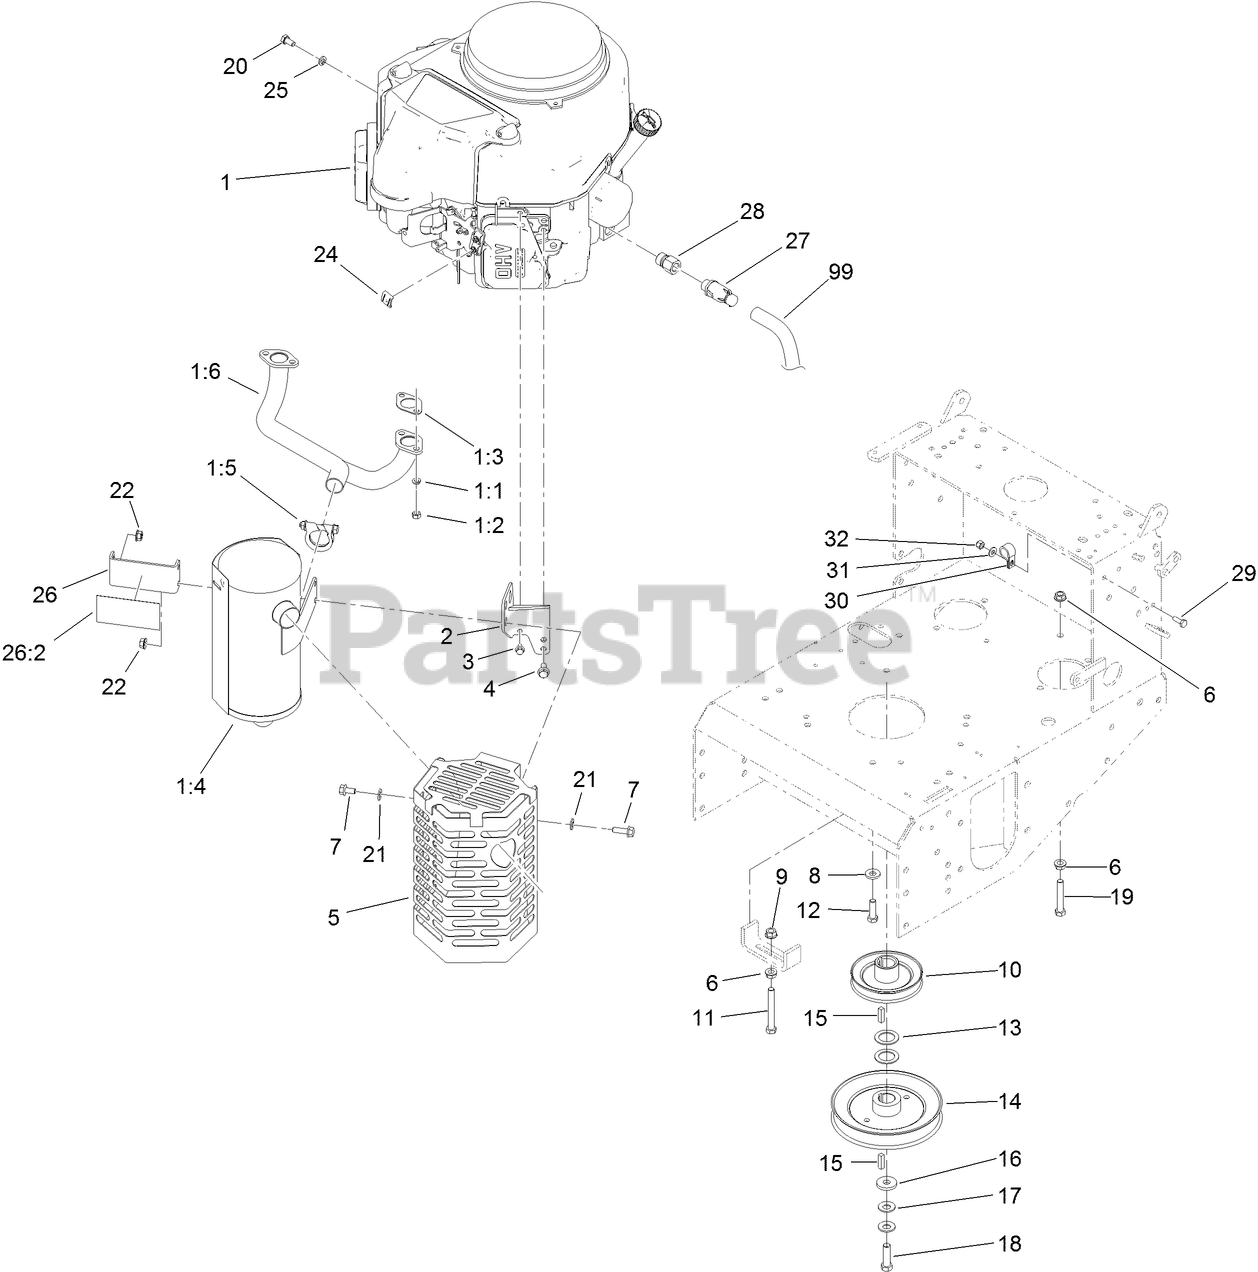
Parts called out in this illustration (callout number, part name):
1:1	WASHER-LOCK
1:3	GASKET-EXHAUST
1:4	MUFFLER-ENGINE
1:5	CLAMP-MUFFLER
1:6	MANIFOLD-EXHAUST
2	BRACKET-MUFFLER
3	SCREW-HHF
4	SCREW-HHF
5	MUFFLER SHIELD ASM
6	NUT-HHF, WHIZ
7	SCREW-HHF
8	WASHER-BELLEVILLE
9	NUT-HF
10	PULLEY
11	SCREW-HH
12	SCREW-HH
13	WASHER-SPACER
14	PULLEY
16	WASHER
17	WASHER-SPRING
18	SCREW-HH
19	SCREW-HH
20	SCREW-HH
21	WASHER-SPRING
22	NUT-HF, LOCK
24	CLAMP-CABLE
25	WASHER-LOCK
26	MUFFLER BRACKET ASM
26:2	FOIL-SHIELD, BRACKET
27	VALVE-DRAIN, OIL
28	ADAPTER
29	SCREW-HH
30	CLAMP-CABLE
31	WASHER-FLAT
32	NUT-LOCK, NI
99	HOSE-DRAIN, OIL
